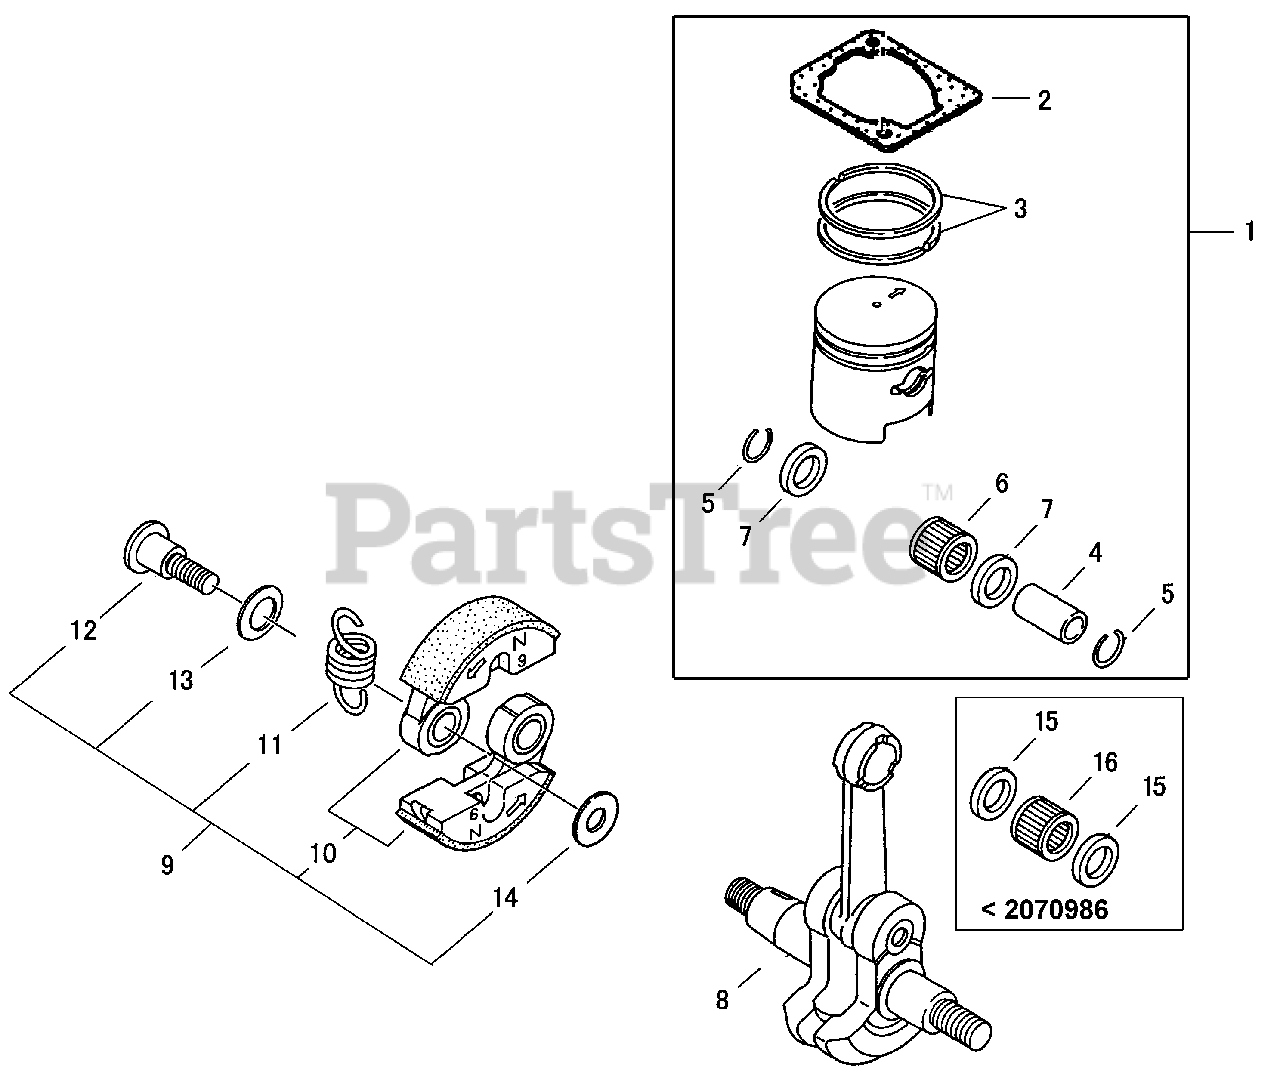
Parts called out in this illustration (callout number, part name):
1	PISTON KIT
2	GASKET, CYLINDER
3	RING, PISTON
4	PIN, PISTON
5	RING, RETAINING
6	BEARING, NEEDLE - 8
7	SPACER, PISTON
8	CRANKSHAFT
9	CLUTCH SHOE ASSY
10	SHOE, CLUTCH
11	SPRING, CLUTCH
12	BOLT, CLUTCH
13	WASHER - SPRING
14	WASHER - 6
15	SPACER, PISTON
16	BEARING, NEEDLE - 8
